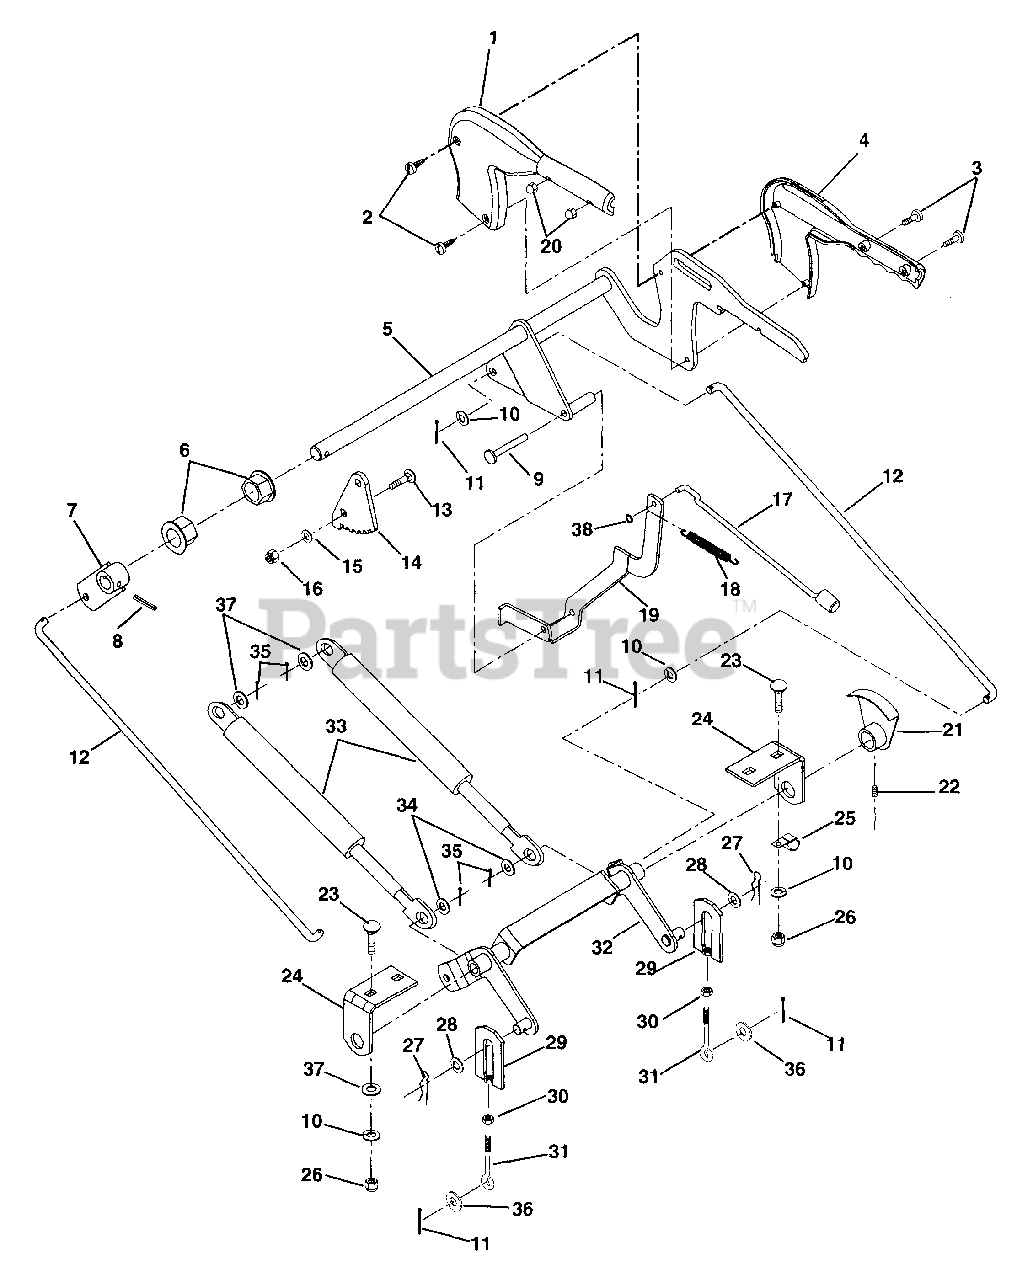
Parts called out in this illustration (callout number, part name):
1	Cover-Lift Right Hand
2	Screw Tapping 12-16 x 1.125
3	Screw-Machine 10-24 x .62
4	Cover-Lift Left Hand
5	Lever-Lift
6	Bushing-Flange .750 x .873
7	Arm-Lift
8	Pin-Groove .250 x 1.25
9	Pivot Pin
10	Washer-Locking .38 x .094
11	Pin-Cotter .12 x 1.0
12	Link-Lift
13	Bolt-Round Head Square Neck .31-18 x .75
14	Quadrant-Lift
15	Washer-Flat-Steel .323 x .625 x .062
16	Nut-Locking-Center .31-18
17	Pin-Lift
18	Spring-Tension .048 x .44 x 2.12
19	Lever-Detent
20	Nut-Low Crown, Acorn 10-24
21	Indicator - Deck Height
22	Screw-Set .25-20 x .25
23	Bolt-Round Head Square Neck .38-16 x .75
24	Bracket-Center Lift
25	J-Clamp
26	Nut-Hex .38-16
27	Pin-Hair External .12 x .31 x 2.37
28	Washer-Flat-Steel .531 x 1.06 x .095
29	Adjuster Link
30	Nut-Hex-Jam .375-16
31	Eye Bolt
32	Lever Center Lift
33	Spring-Gas Compression .315 x .75 x 10.00
34	Washer-Flat-Steel .38 x .875 x .083
35	Pin-Cotter .12 x .75
36	Washer-Flat-Steel .656 x 1.31 x .095
37	Washer-Flat-Steel .406 x .812 x .065
38	Ring-Retaining-External .250 x .010
